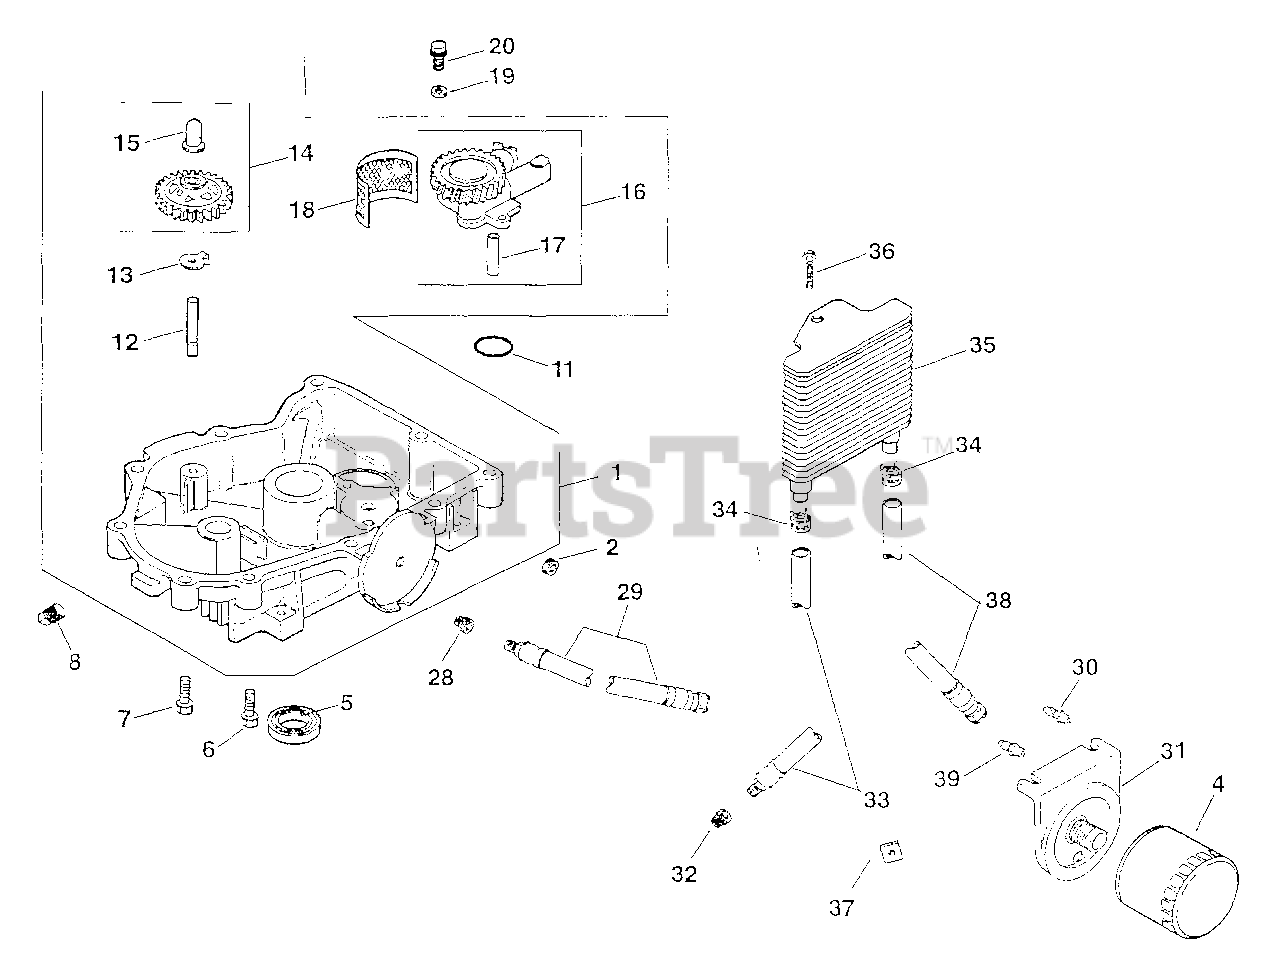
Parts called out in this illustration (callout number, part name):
2	PLUG, PIPE CTSK 3/8" USE 25 139 62-S
4	OIL FILTER
5	SEAL, OIL (KM)-USE 25 032 06-S
6	SCREW, FLG M8X1.25X45
7	SCREW, HEX FLANGE -USE 24 086 17-S
12	SHAFT, GOVERNOR GEAR
14	KIT, GOVERNOR GEAR W/PIN
15	PIN, GOVERNOR REGULATING
18	SCREEN, OIL-USE 24 162 26-S
19	WASHER - USE M-631005
20	SCREW - USE M-645025
36	SCREW, TAP M6X1.7X18
37	NUT, PLASTIC (KM)-USE 25 100 37-S
